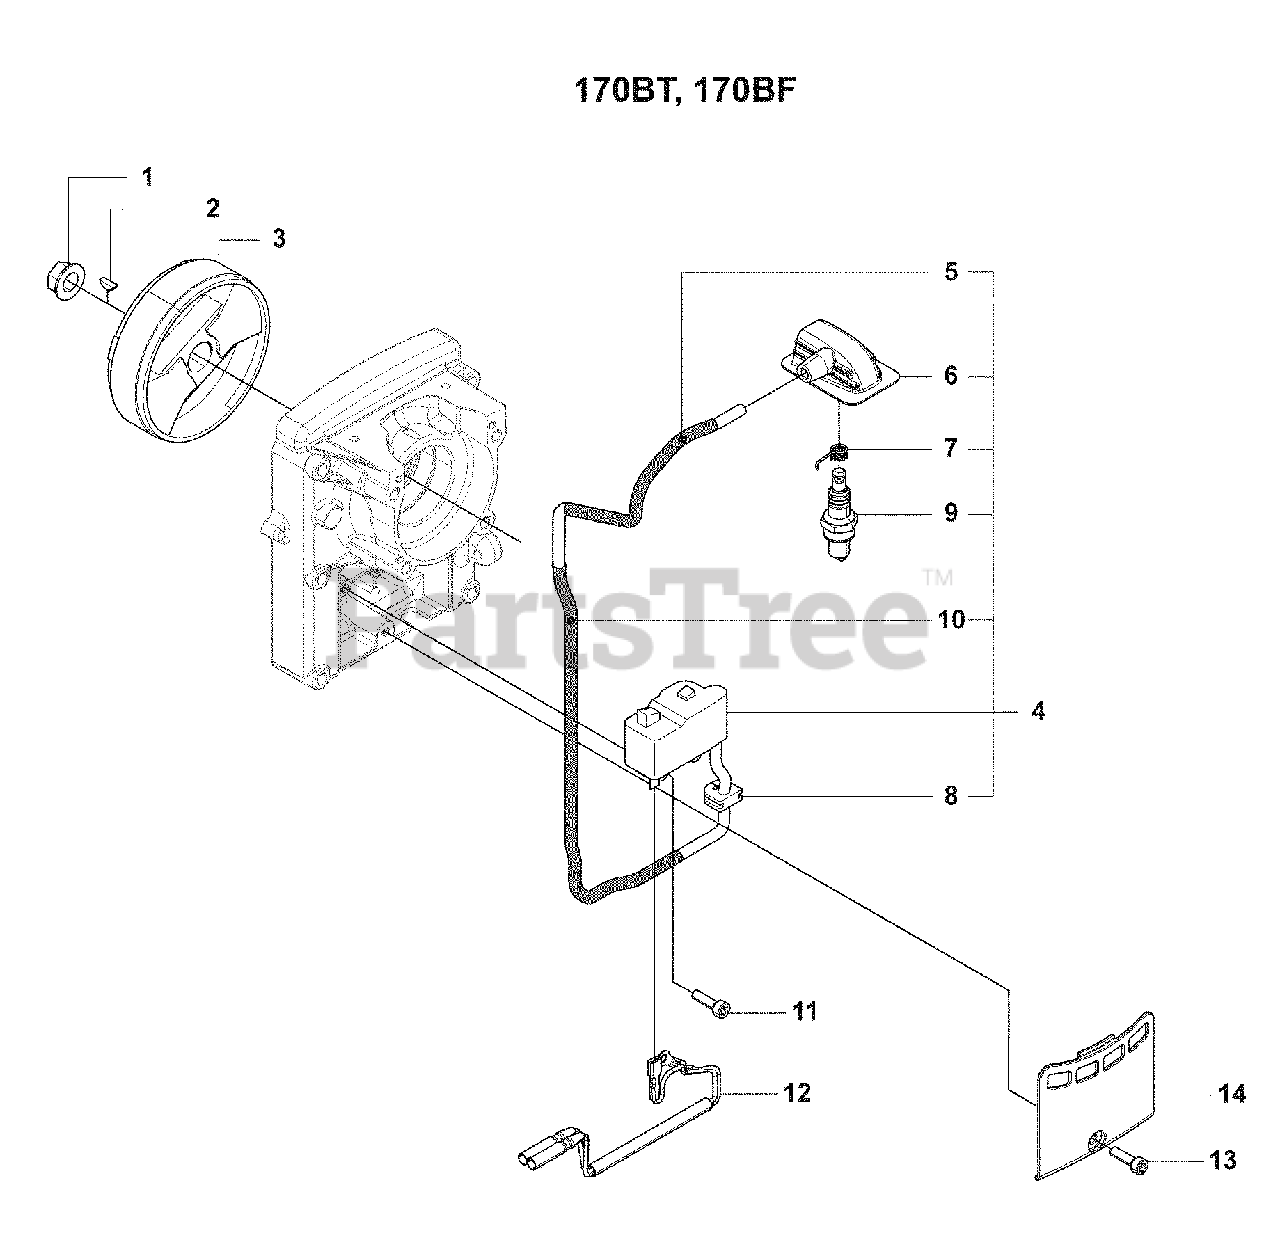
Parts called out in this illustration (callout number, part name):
1	Nut
2	Flywheel Key
4	Ignition Coil
6	Cap
7	Plug Spring
9	Spark Plug, CMR7H BLYB
11	Torx Bolt, M4 X L16
12	Cord, Complete
13	Torx Bolt, M4 X L16
